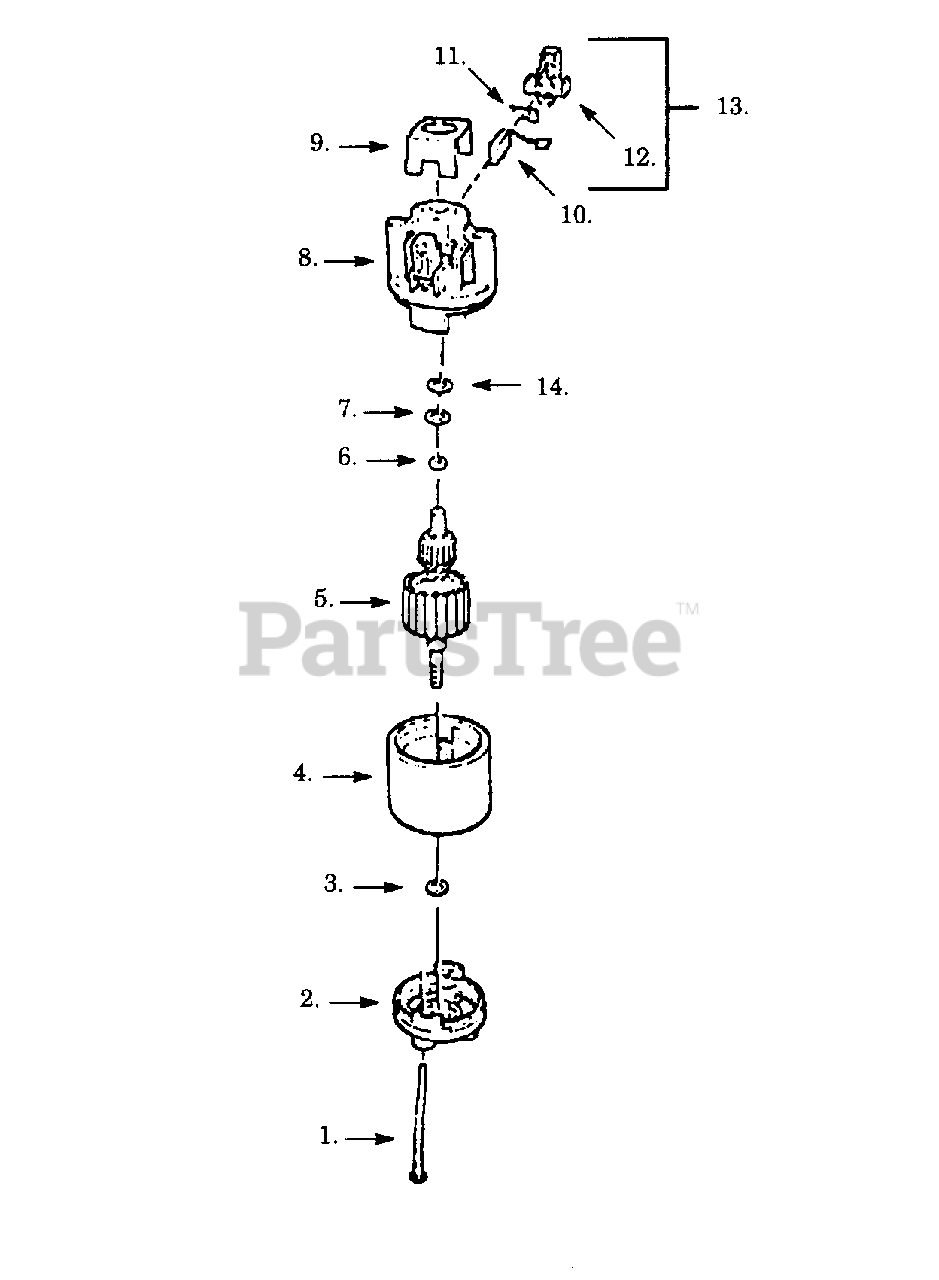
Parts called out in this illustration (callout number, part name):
2	Endbell Ass'y. (Drive)
4	Field Ass'y.
5	Armature Ass'y.
8	Endbell Ass'y. (Brush)
9	Insulator
10	Carbon Brush
11	Brush Spring
12	Brush Holder
13	Brush Kit (Inc. 10.11,12)
14	Retaining Ring
